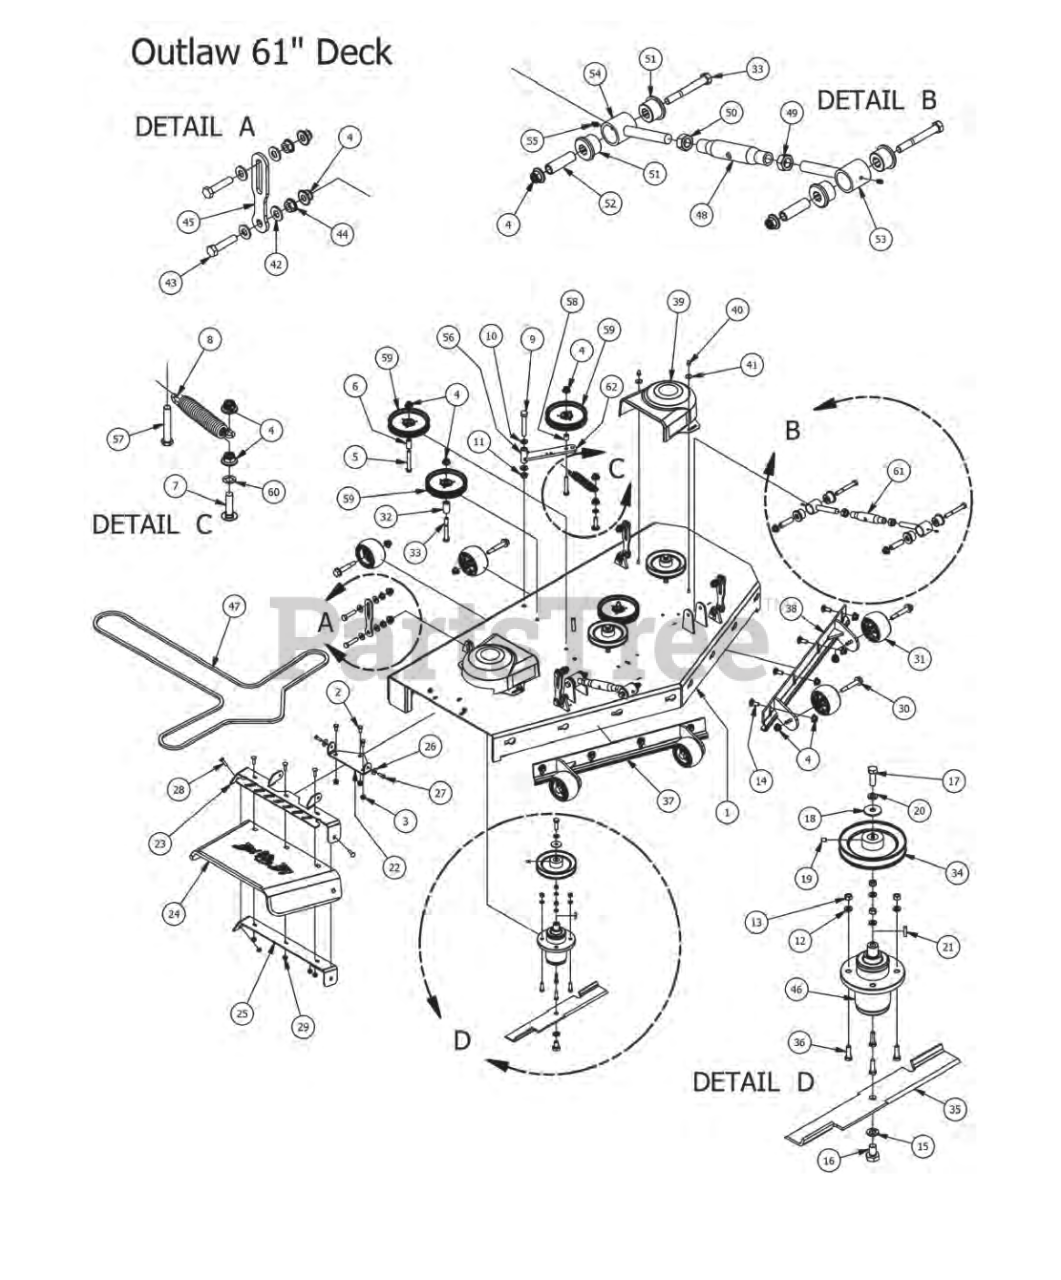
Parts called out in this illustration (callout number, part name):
1	2015 61" Deck
2	3/8" x 3/4" Hex Bolt
3	3/8" Flange Nut
4	1/2-13 Nylon Flange Nut-Orange
5	1/2 x 3 1/2 Flange Bolt Grade 8
6	502 ID X.75 OD X 1.500 Leng
7	1/2 x 2" Carriage Bolt
8	2015 Deck Idler Spring Outlaws
9	5/8" x 4" Hex Bolt
10	635 ID Plastic Washer
11	5/8-11 Nylon Insert Jam Half Nut
12	3/8 Lockwasher Zinc
13	3/8-16 Hex Nuts Zinc
14	1/2" x 1 1/4 Carriage Bolt
15	5/8" Lock Washer
16	5/8" x 1 1/2" Gr8 Hex Bolt (Fine)
17	1/2"-20 x 1 1/2-Grade 5 Fine Thread Bolt
18	1/2 Belleville Washer
19	5/16 Set Screw
20	1/2" Lock Washer
21	1/4" x 1" Key
22	Discharge Chute Hanger (deck mounted)
23	60" Discharge Chute Upper Hanger
24	Rubber Discharge Chute
25	60 Discharge Lower Bracket
26	360 ID Plastic Washer
27	5/16" x 1" Bolt
28	5/16" x 1 1/4" Carriage Bolt
29	5/16" Flange Nut Zinc W/Serrations
30	Deck Wheel Bolt
31	Anti-Scalp Rollers
32	1 3/4" Pulley Spacer
33	1/2" x 4" Bolt (Grade 8)
34	6 1/4" Drive Pulley
35	61 inch Fusion Blade
36	3/8" x 1 1/4" Hex Bolt
37	61 Deck Adustable Front (Right)
38	61 Deck Adustable Front (Left)
39	Pulley Cover
40	Acorn nut-pulley Cover
41	.360 ID Plastic Washer-Black
42	505 Nylon Spacer
43	1/2-13X 2-1/4 GR Hex Bolts
44	1/2" Flange Nut
45	Deck Hanging Tab
46	OUTLAW SPINDLE ASSEMBLY
47	B226 Belt for 1100cc Diesel
49	3/4-10 Left-Handed Hex Nuts Zinc
50	3/4-10 Hex Nuts Zinc
53	Turn Left-Handed
54	Right-Handed End
55	1/4" Press in Grease Fitting
56	Deck Idler
57	1/2-13 x GR 5 Hex Bolt Zinc
58	3/4 OD x 1/2 ID x 314 Length
59	5-3/4 Idler Pulley
60	.517 Square Hole Round Washer
61	Tumbuckle Assembly
62	Deck Idler Assembly Includes parts: 4,10,59,60,61
